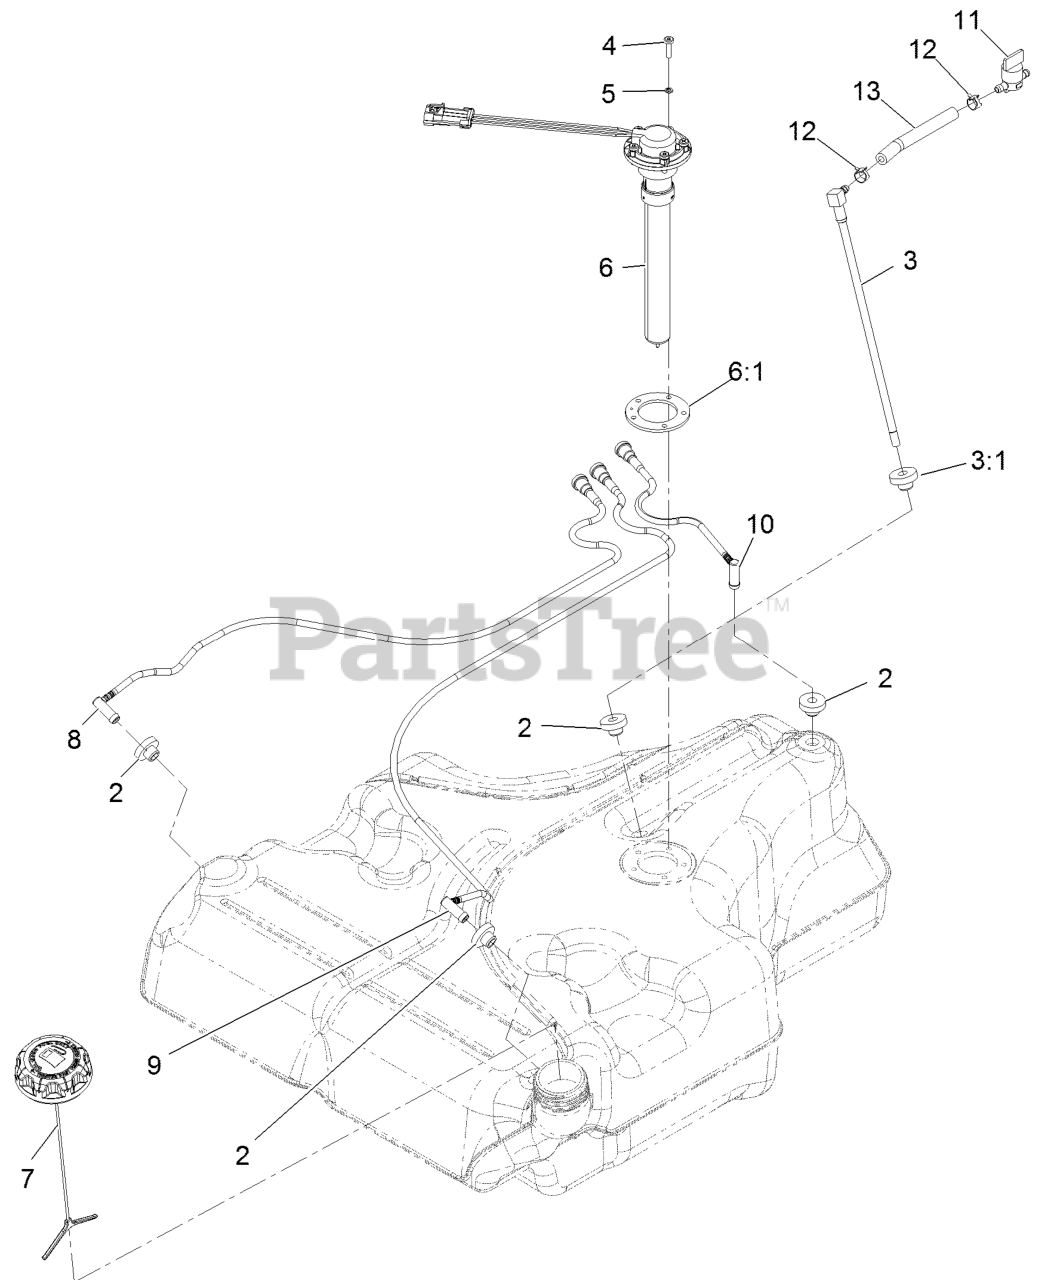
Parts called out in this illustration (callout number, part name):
2	BUSHING
3	FUEL LINE KIT (WITH GROMMET)
3:1	BUSHING
4	SCREW-PAN
5	WASHER-LOCK
6:1	GASKET-SENDER, FUEL
7	CAP-FUEL, RATCHETING
8	RH VENT LINE KIT (WITH GROMMET)
9	LH VENT LINE KIT (WITH GROMMET)
10	REAR VENT LINE KIT (WITH GROMMET)
11	VALVE-FUEL
12	CLAMP-HOSE
13	HOSE-FUEL
